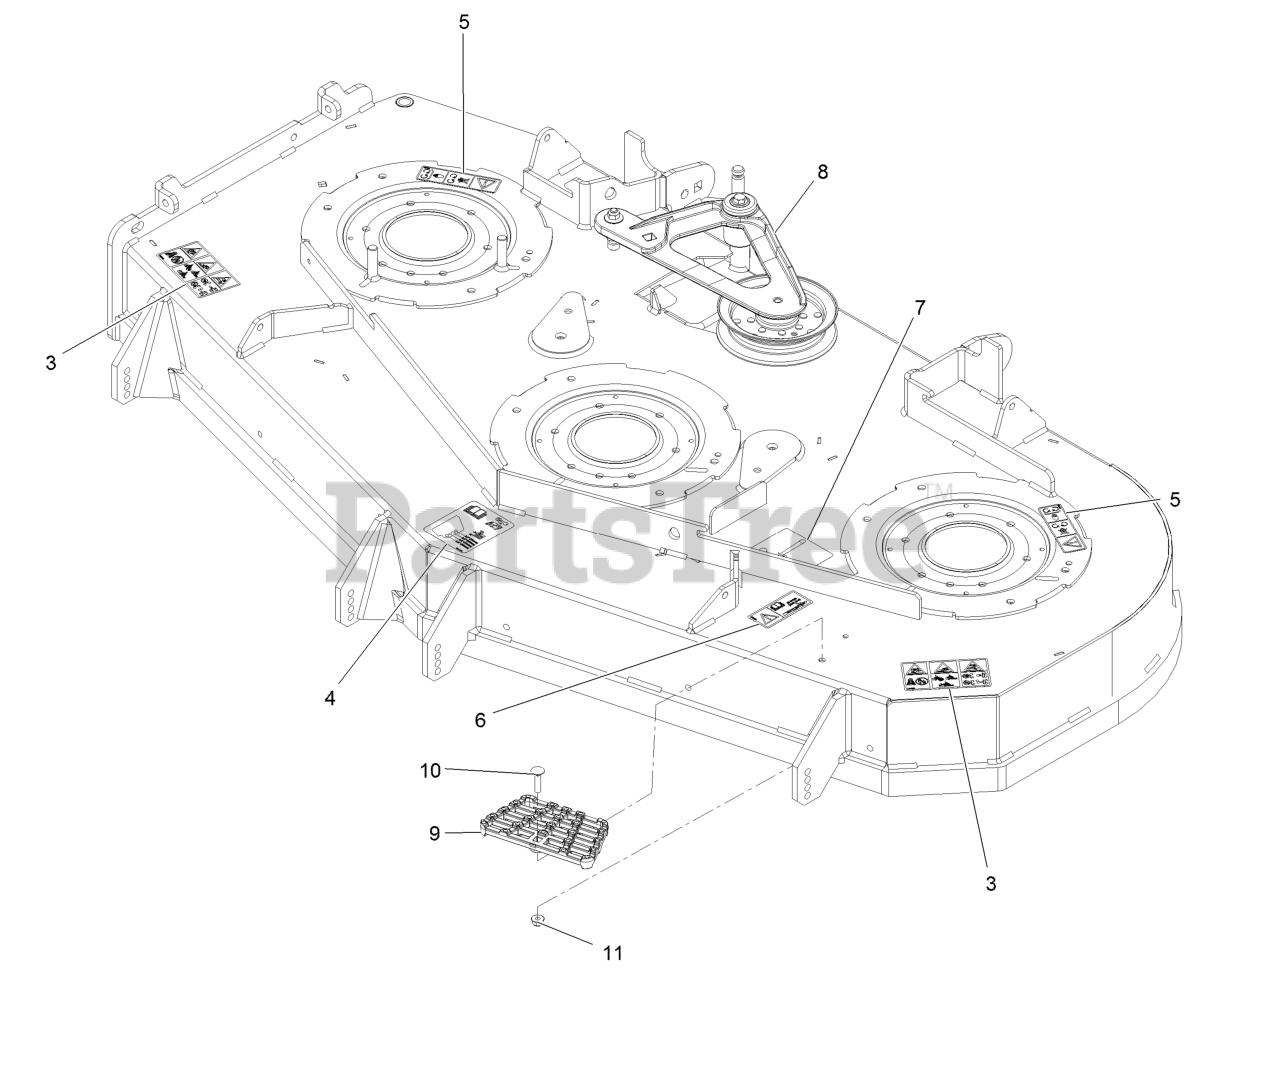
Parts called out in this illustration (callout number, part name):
3	Decal-Danger Thrown Objects
4	Decal-Roller, Anti-Scalp
5	Decal-Cover, Missing
6	Decal-Bolt Torque
7	Decal-Belt Routing
8	Deck Idler ASM
9	Step-Deck
10	Bolt-Carriage 5/16-18 X 1 1/4
11	Nut-Nyloc 5/16-18 Flg
